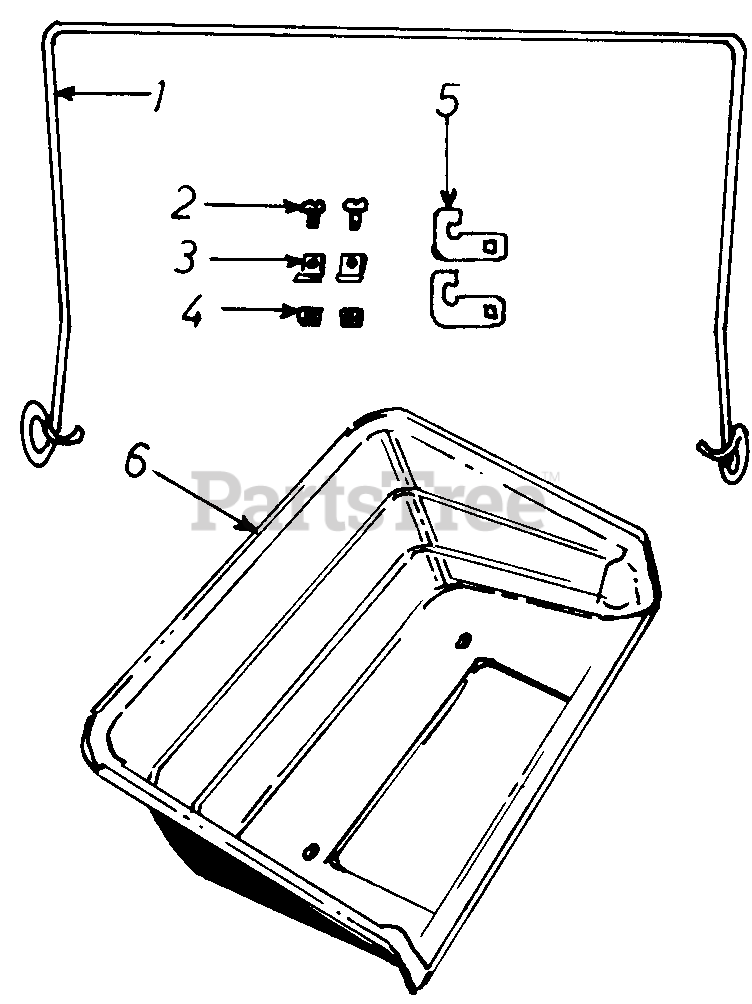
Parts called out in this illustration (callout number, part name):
1	Spring Mounting Loop
2	Truss Sems Scr. #10-24 x 3/8" Lg.
3	Speed Clamp
4	Square nut #10-24
5	Mounting Hook
6	Grass Catcher
